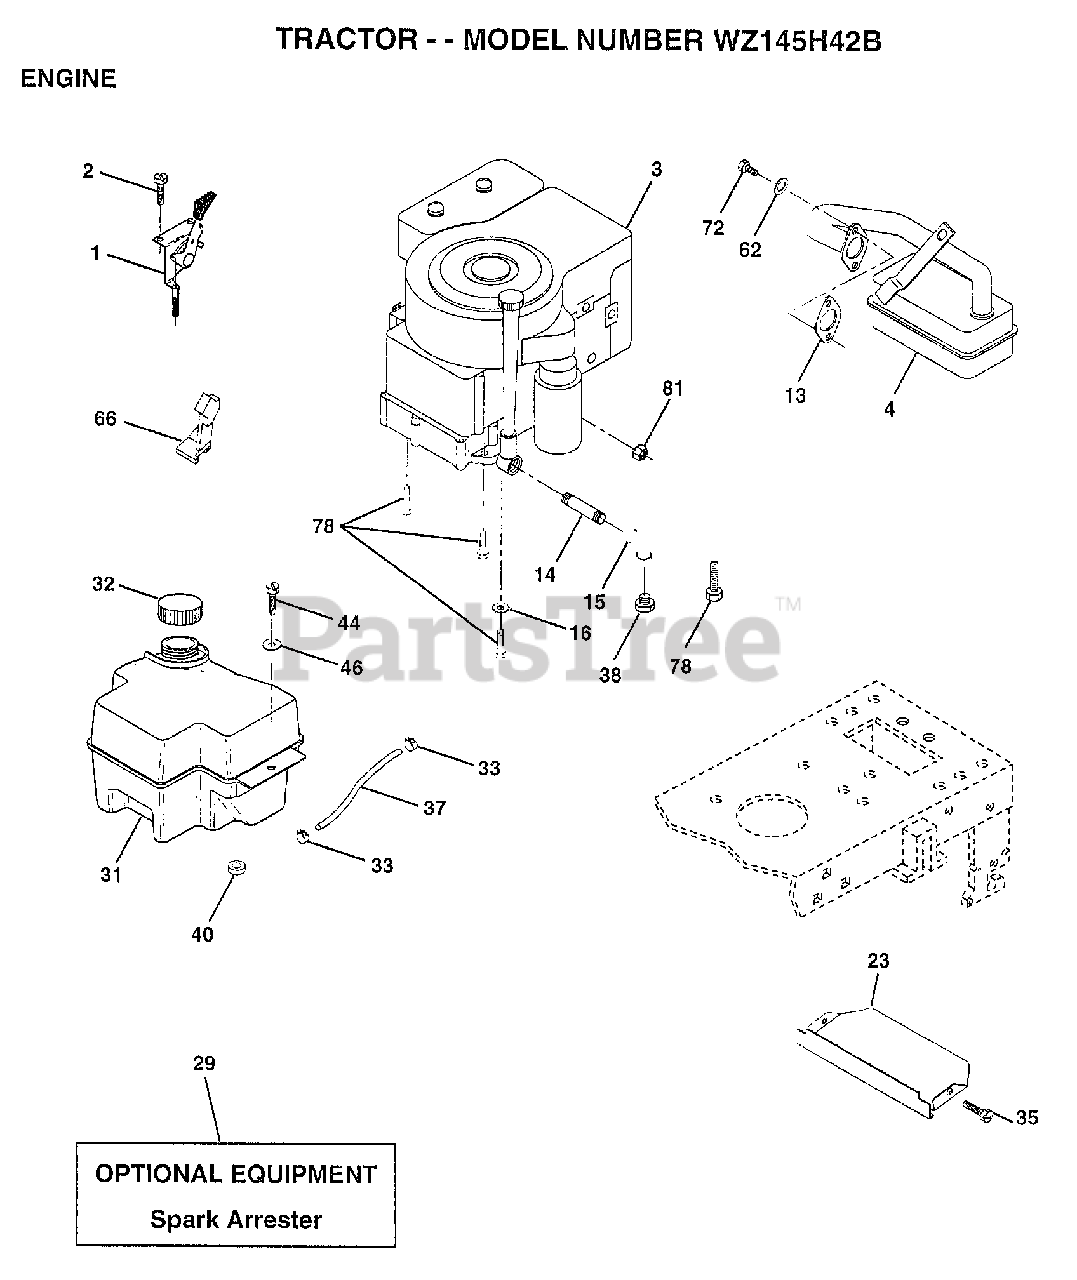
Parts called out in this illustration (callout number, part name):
1	CONTROL.THTL.23.5
2	SCREW LT
4	MUFFLER
14	PIPE NIPPLE
15	ELBOW
16	LOCKWASHER
23	SHIELD.BRN/DBR.GD
31	TANK.FUEL.FRONT.
32	CAP ASM FUEL
33	HOSE CLAMP
35	SCREW
37	LINE FUEL
44	SCREW HEX CRT
46	WASHER
62	LOCKWASHER
66	"STOP,DASH THROTT"
72	SCREW
78	SCREW
81	NUT
